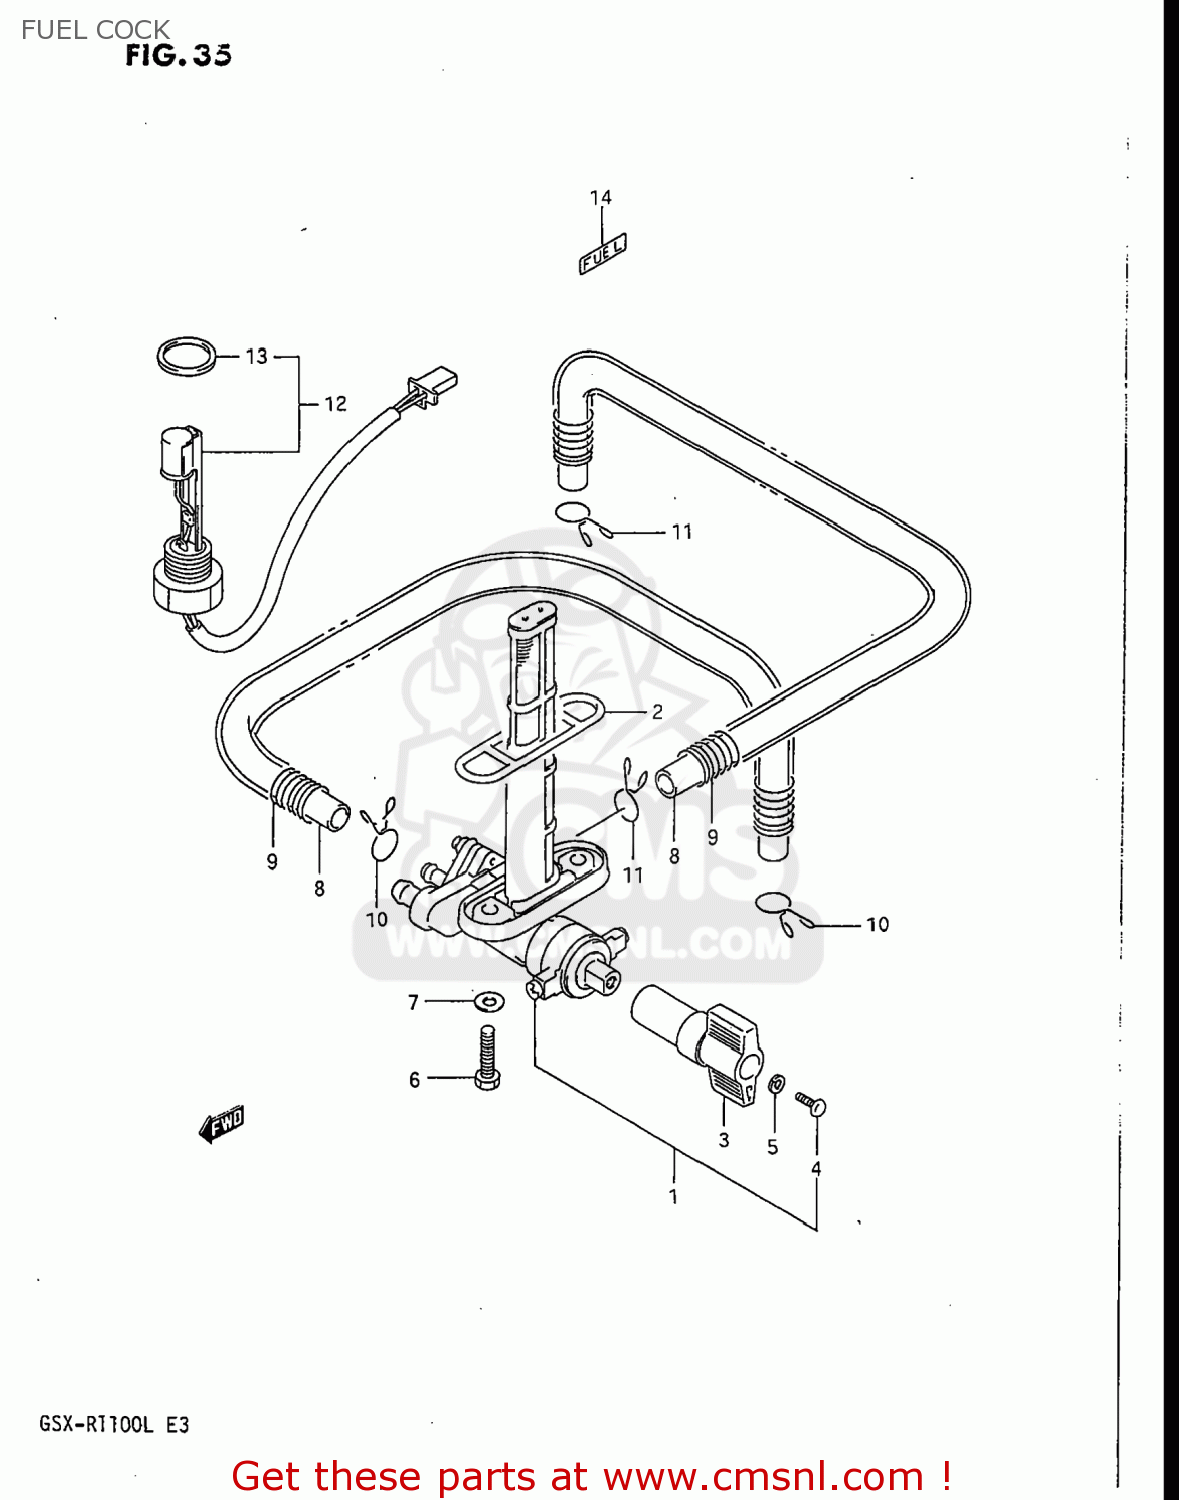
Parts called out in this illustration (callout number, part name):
1	COCK ASSEMBLY,FUEL
2	O RING,FUEL TANK JOINT
3	LEVER,FUEL COCK
4	SCREW
5	LOCK WASHER
6	BOLT(6X20)
7	GASKET(6.4X11.5X0.8) (NAS)
8	HOSE
9	SPRING
10	CLIP
11	CLIP
12	GAUGE ASSEMBLY,FUEL LEVEL
13	GASKET,FUEL LEVEL GAUGE (NAS)
14	LABEL (FUEL)
